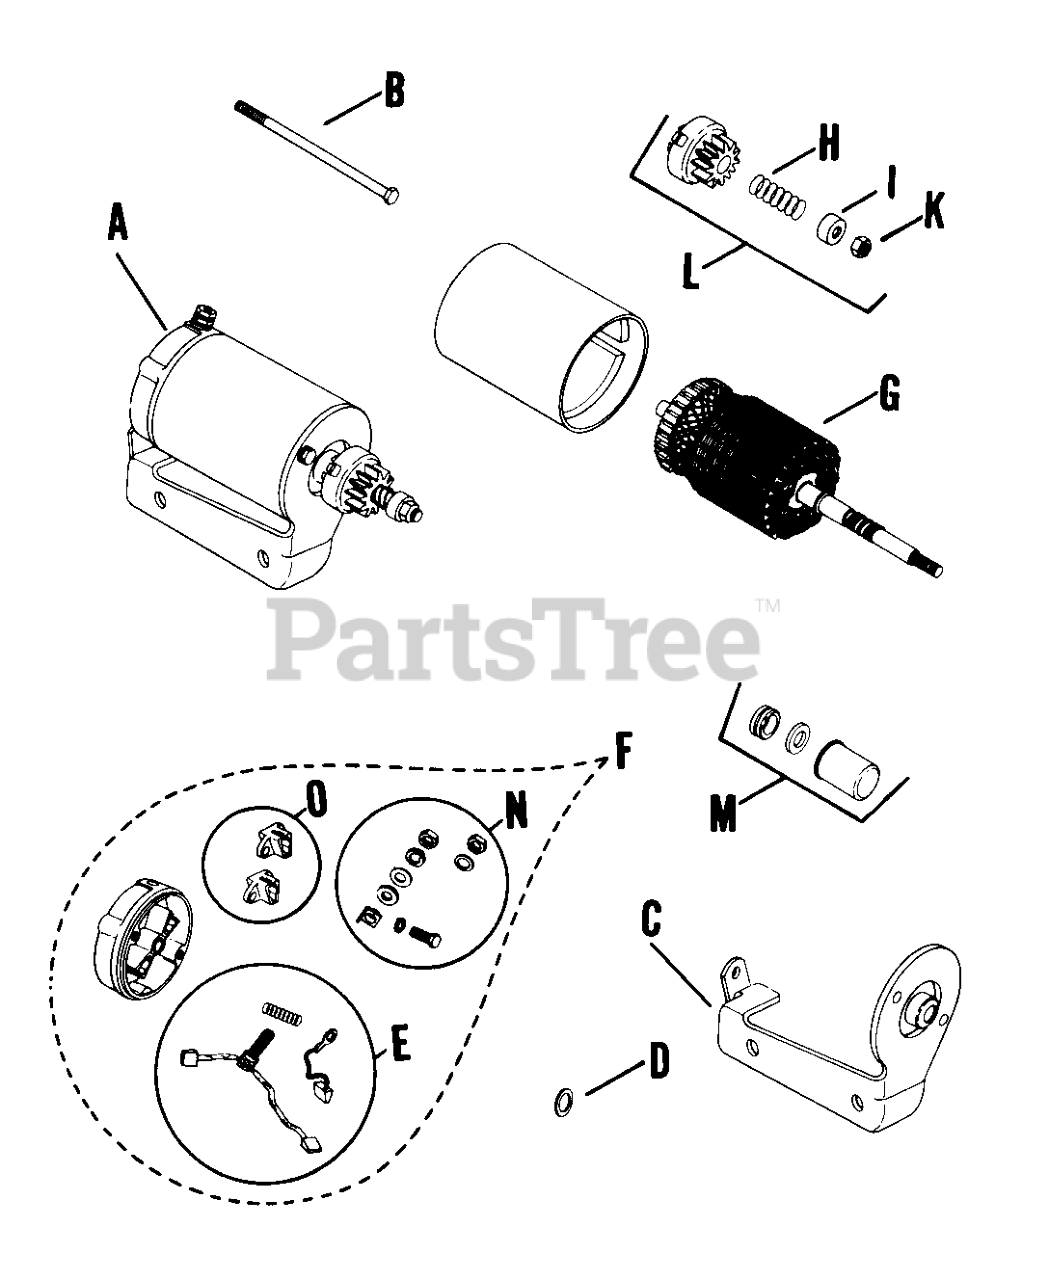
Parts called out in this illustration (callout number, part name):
A	STARTER - USE A-237534
B	BOLT - USE 237758
D	WASHER - USE 47 468 02
E	KIT - USE 277613
F	CAP - USE 47 755 12
G	ARMATURE - USE 47 170 01
H	SPRING - USE 45 089 03
L	KIT DRIVE - USE 47 755 07
M	KIT - USE 47 755 13
